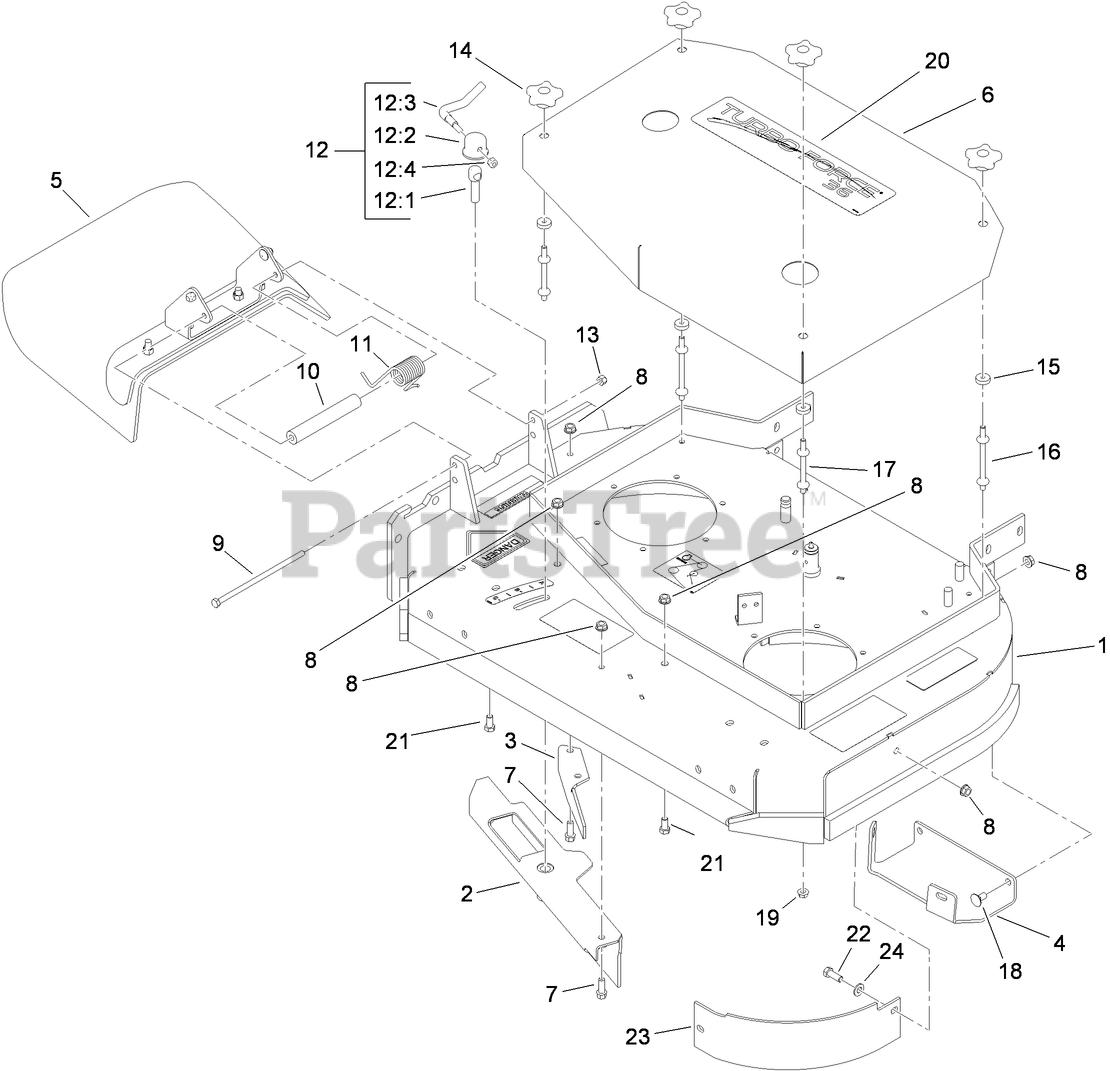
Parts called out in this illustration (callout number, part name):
1	DECK ASM
2	BAFFLE-ADJUSTABLE
3	BAFFLE-DISCHARGE
4	PLATE-SKID
5	DEFLECTOR ASM
6	COVER-DECK
7	SCREW-HWH
8	NUT-HHF, WHIZ
9	SCREW-HH
10	SPACER
11	SPRING-TORSION
12	LEVER ASM
12:1	Screw-Lock
12:2	CAP-LOCK
12:3	Lever-Lock
12:4	NUT-LOCK, NI
13	NUT-LOCK, NI
14	KNOB-HANDLE
15	WASHER
16	STUD-SHIELD, BELT (LONG)
17	STUD-SHIELD, BELT (SHORT)
18	SCREW-CARR
19	NUT-HF
21	SCREW-HH
22	SCREW-HH
23	BAFFLE-FRONT, LH
24	WASHER-FLAT
